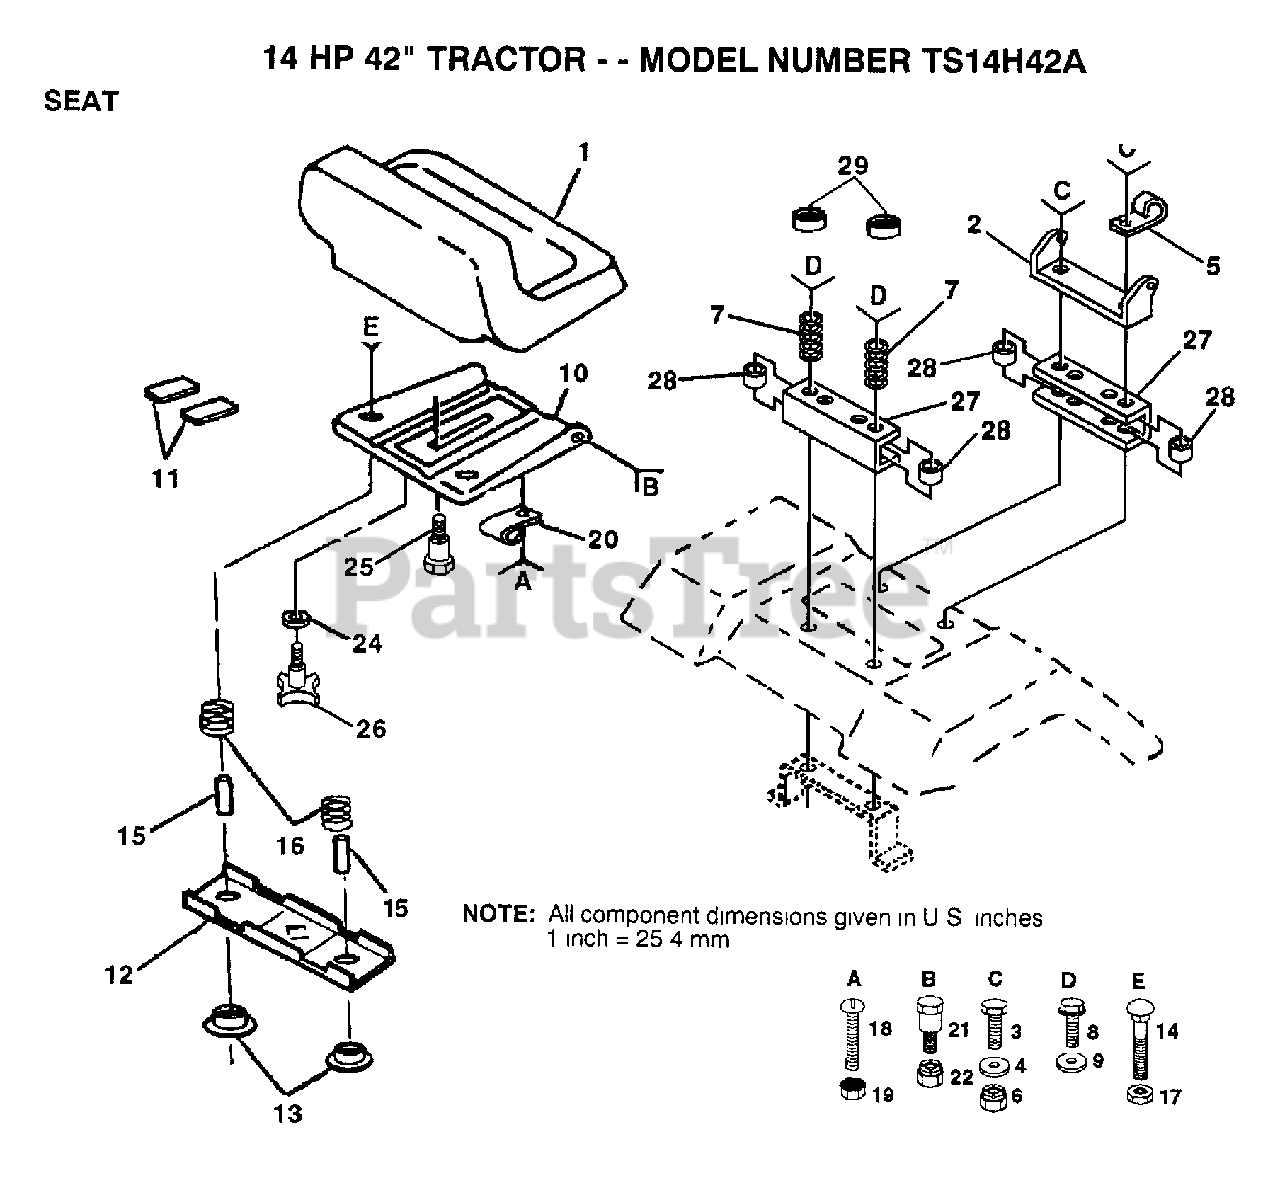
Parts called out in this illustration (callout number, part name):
3	BOLT
4	WASHER PM
5	CLIP T
7	SPRING COMPRESSIO
8	SCREW
9	WASHER
11	STRIP FORM
12	BRKT SWITCH
13	BUSHING
15	SPLIT SPACER
16	SPRING
19	"NUT,KEPS"
24	WASHER
25	"BOLT,SHOULDER"
26	"KNOB 1/2"" YT"
27	SEAT SPACER
28	SPLIT SPACER
29	CAP SPRING
